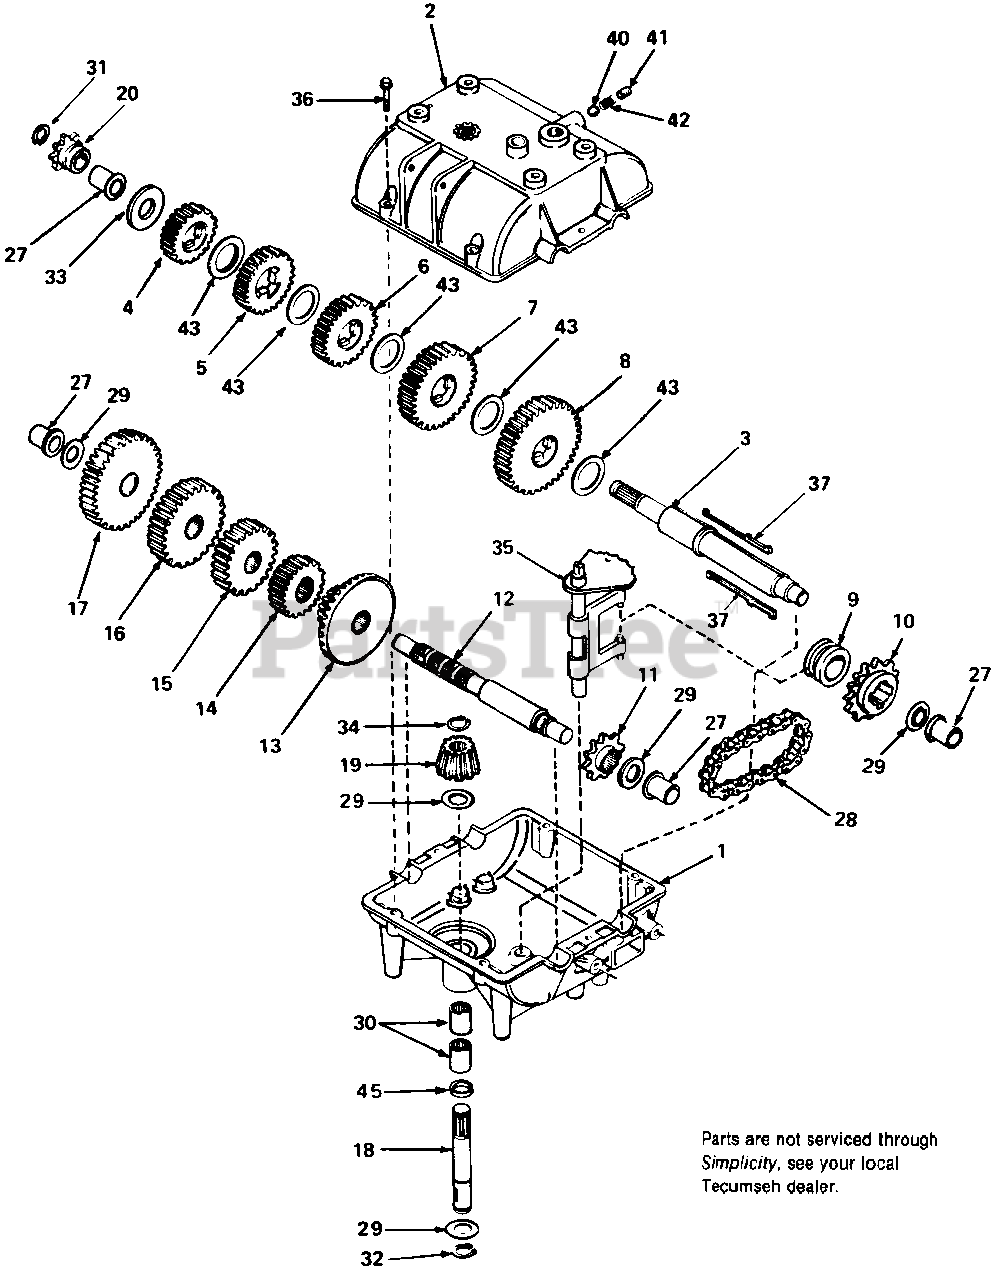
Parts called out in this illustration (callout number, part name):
1	CASE, Transmission
2	COVER, Transmission
3	SHAFT, Output
4	GEAR, Spur (20 teeth)
5	GEAR, Spur (22 teeth)
6	GEAR, Spur (25 teeth)
7	GEAR, Spur (30 teeth)
8	GEAR, Spur (35 teeth)
9	COLLAR, Shift
10	SPROCKET (18 teeth)
11	SPROCKET (9 teeth)
12	SHAFT, Counter
13	GEAR, Bevel (42 teeth & 15 tooth spur gear)
14	GEAR, Spur (20 teeth)
15	GEAR, Spur (25 teeth)
16	GEAR, Spur (28 teeth)
17	GEAR, Spur (30 teeth)
18	SHAFT, Input
19	BEVEL PINION, Input
20	SPROCKET (8 teeth)
27	BUSHING, Flanged
28	CHAIN, Roller (No. 41 chain, 24 links)
29	RACE, Thrust
30	BEARING, Needle
31	RING, Retaining
32	RING, Retaining
34	RING, Retaining
35	ROD & FORK ASSY., Shift
36	SCREW, Hex Hd., Taptite, 1/4-20 x 1-1/4
40	BALL, Steel, 5/16
41	SCREW, Set, 3/8-16 x 3/8
43	WASHER, Thrust
45	RING, Square Cut
